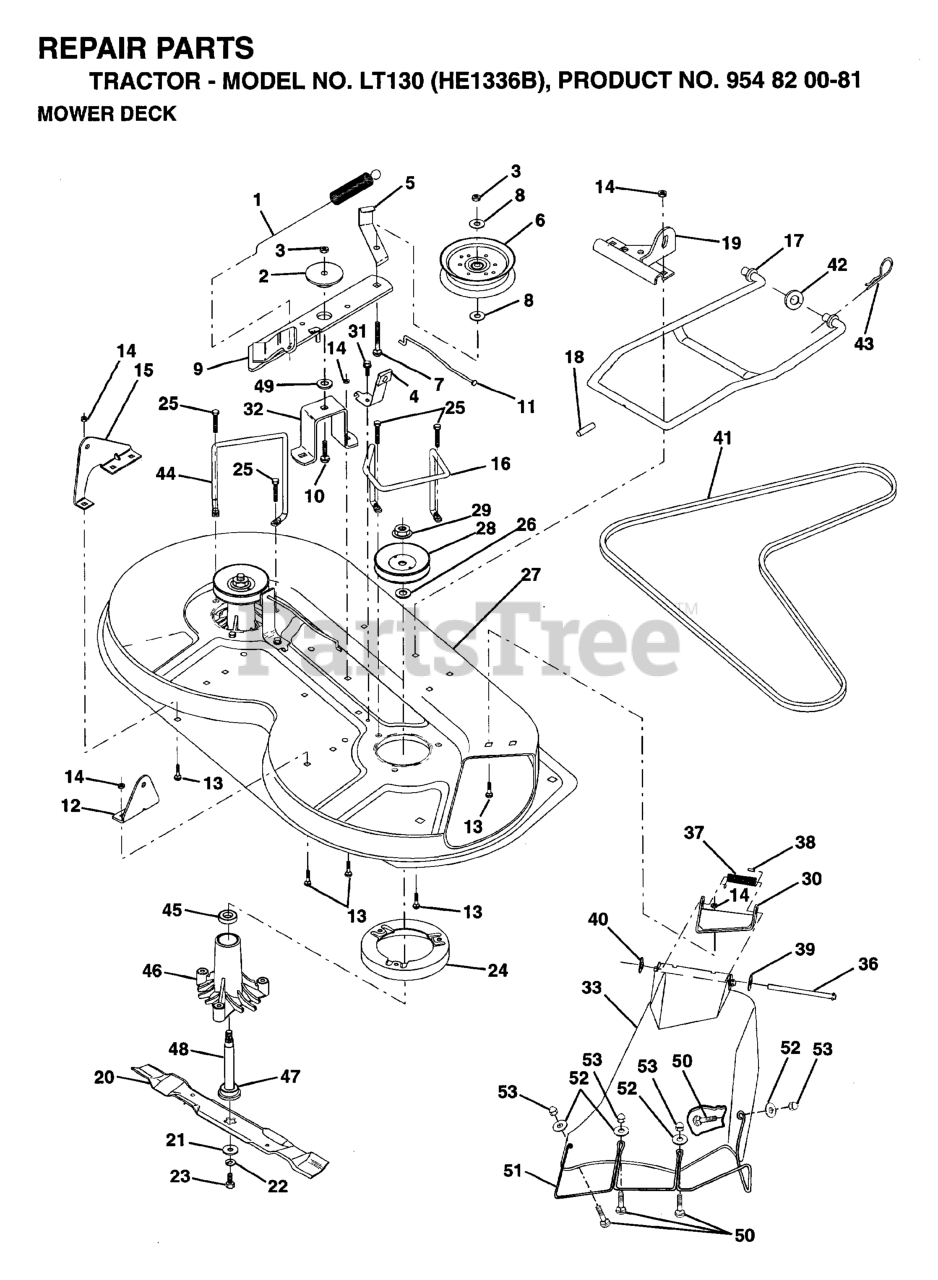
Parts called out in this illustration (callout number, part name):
1	SPRING-MOWER CLUTCH
2	SPACER RETAINER
4	BRAKE ASSEMBLY
5	IDLER BELT GUIDE
6	PULLEY.IDLER.FLAT.MOWER.BLK.PT
8	WASHER
9	IDLER ARM ASSY
10	BOLT.3/8-14X1.25
12	BRKT LIFT REAR
13	RP BOLT 5/16-18 X3/4 ZN/YEL GR
14	LOCKNUT
15	BRKT LIFT REAR LH
16	KEEPER RH
17	MOWER LINK STABILIZER
18	PIN GROOVE
19	BRKT LINK STABILIIZER
20	BLADE, HI-LIFT 36" PREMIUM
21	WASHER.BLADE
22	LOCKWASHER
23	BLADE BOLT
24	STRIPPER
25	SCREW
26	WASHER
27	MOWER HOUSING
28	PULLEY
29	NUT
30	BRACKET ASM DEFLECTOR
31	Screw 5/16-18 x 1/2 Hex, Self Tapping 5/16-18 x 1/2
32	SUPT,IDLER ARM
33	DEFLECTOR
36	HINGE ROD
37	SPRING TORSION
38	CAP-SLEEVE LT
39	Washer 11/32 x 5/8 x 16 Ga SD
40	NUT PUSH M
42	WASHER
43	SPRING RETAINER
46	HOUSING.MANDREL.VENTED (MACHD)
47	BEARING.BALL.#6204.(MANDREL)
48	SHAFT ASM VENT
49	HARDENED WASHER
50	SCREW
52	REPL BY 734 11 46-01
53	NUT
